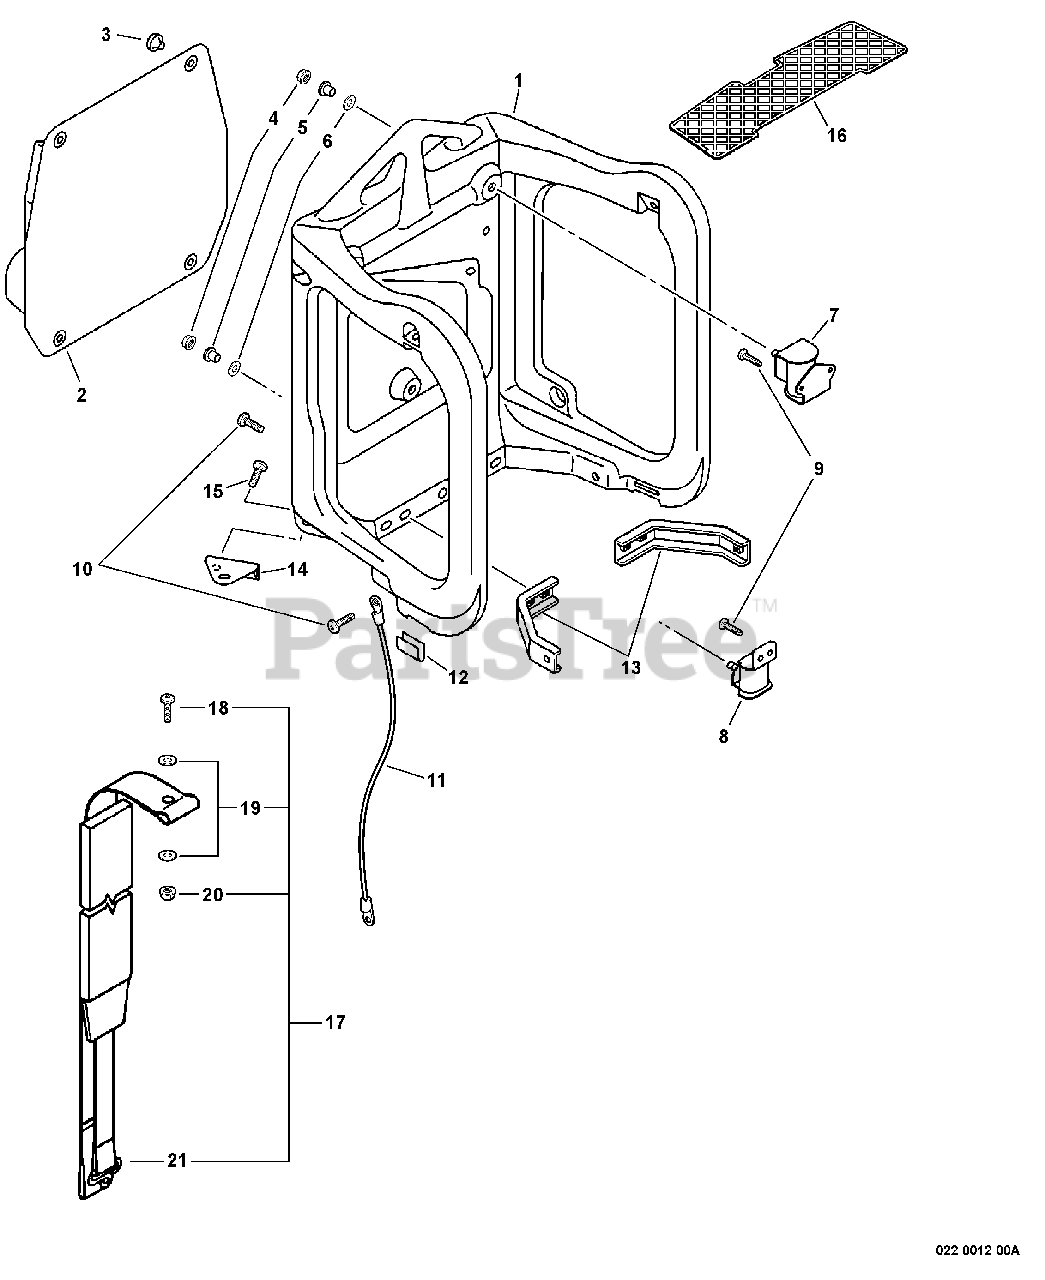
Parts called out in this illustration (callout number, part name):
1	FRAME, BACKPACK
2	CUSHION, BACKPACK
4	NUT, FLANGE M5
8	CUSHION
9	SCREW 5×16
10	SCREW 5×14
11	LEAD - GROUND
12	BUMPER
13	CONNECTOR, FRAME
14	BRACKET, HANGER
15	SCREW 5×20
16	GUARD, DEBRIS
17	BACKPACK STRAP ASSY
18	SCREW 5×14
19	WASHER 5.5×18×1
20	NUT, FLANGE M5
21	RING, HARNESS
